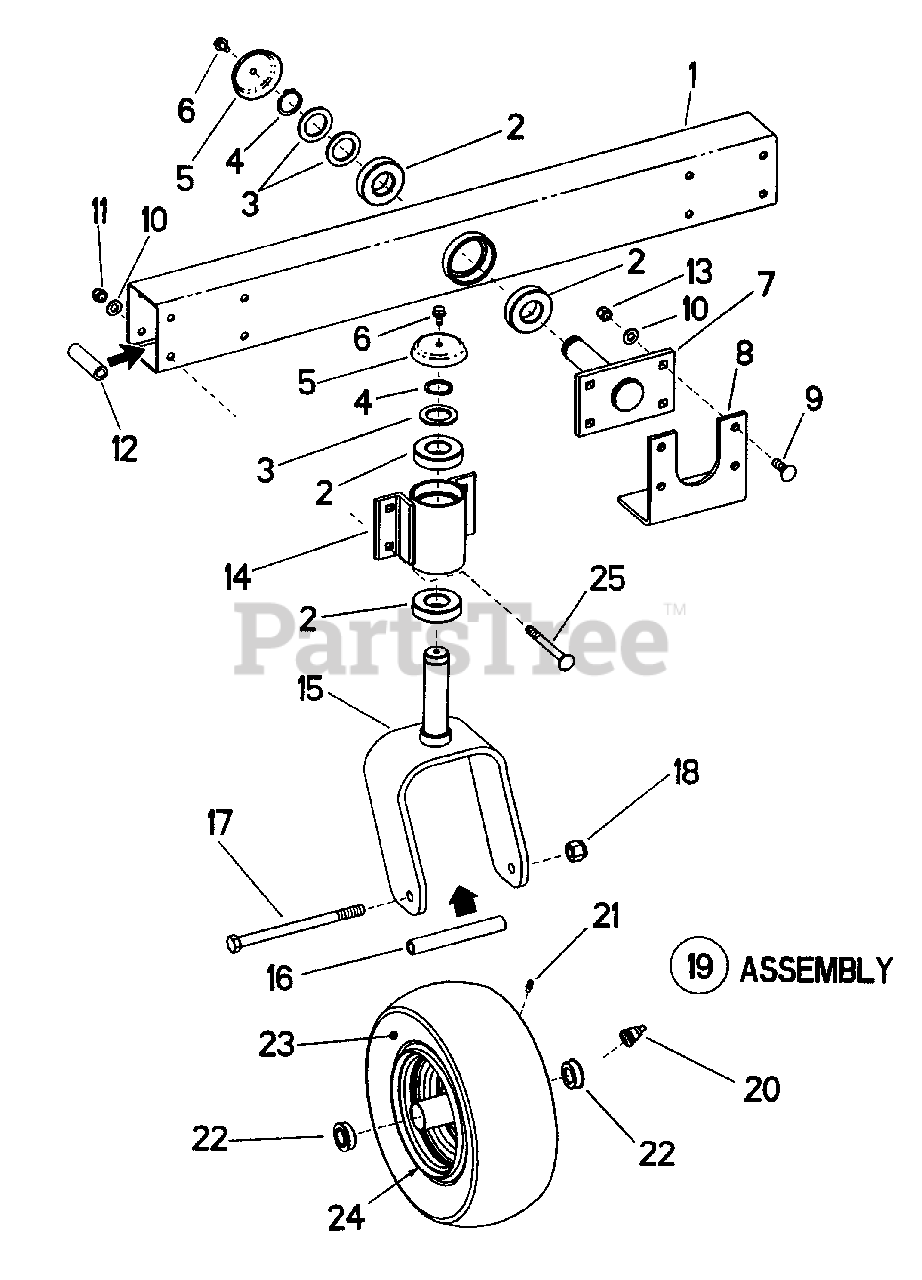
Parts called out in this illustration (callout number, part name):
1	WELDMENT, Axle
2	BEARING, 30mm x 62mm
3	WASHER, 1-1/4 I.D. x 1-7/8" O.D. Flat
4	RING, 1-3/16 External Retaining
5	CAP, Caster Shaft
6	SCREW, 5/16-18 x 5/8" Self-Tapping
7	WELDMENT, Front Axle Pivot
8	BRACKET, Axle Stop
9	BOLT, 3/8-16 X 1-1/2" Short Neck Carriage, Grade 5
10	WASHER, 3/8" Flat
11	NUT, 3/8-16 HEX NYLON LOCK
12	TUBE, 13/32 I.D. x 3/4 O.D. x 2.70
13	NUT, 3/8-16 Hex Center Lock, Grade B or 5
14	WELDMENT, Caster Support
15	WELDMENT, Caster Yoke
16	SPACER, Bearing
17	BOLT, HEX, 1/2-13 X 7, GD 8, YZ
18	NUT, 1/2-13 Nyloc
19	ASSEMBLY, Tire & Rim
20	VALVE, Air
21	FITTING, Lube
22	BEARING
23	TIRE, 13 x 5.00-6, 4 Ply
25	BOLT, 3/8-16 x 4" Square Neck Carriage, Grade 5
